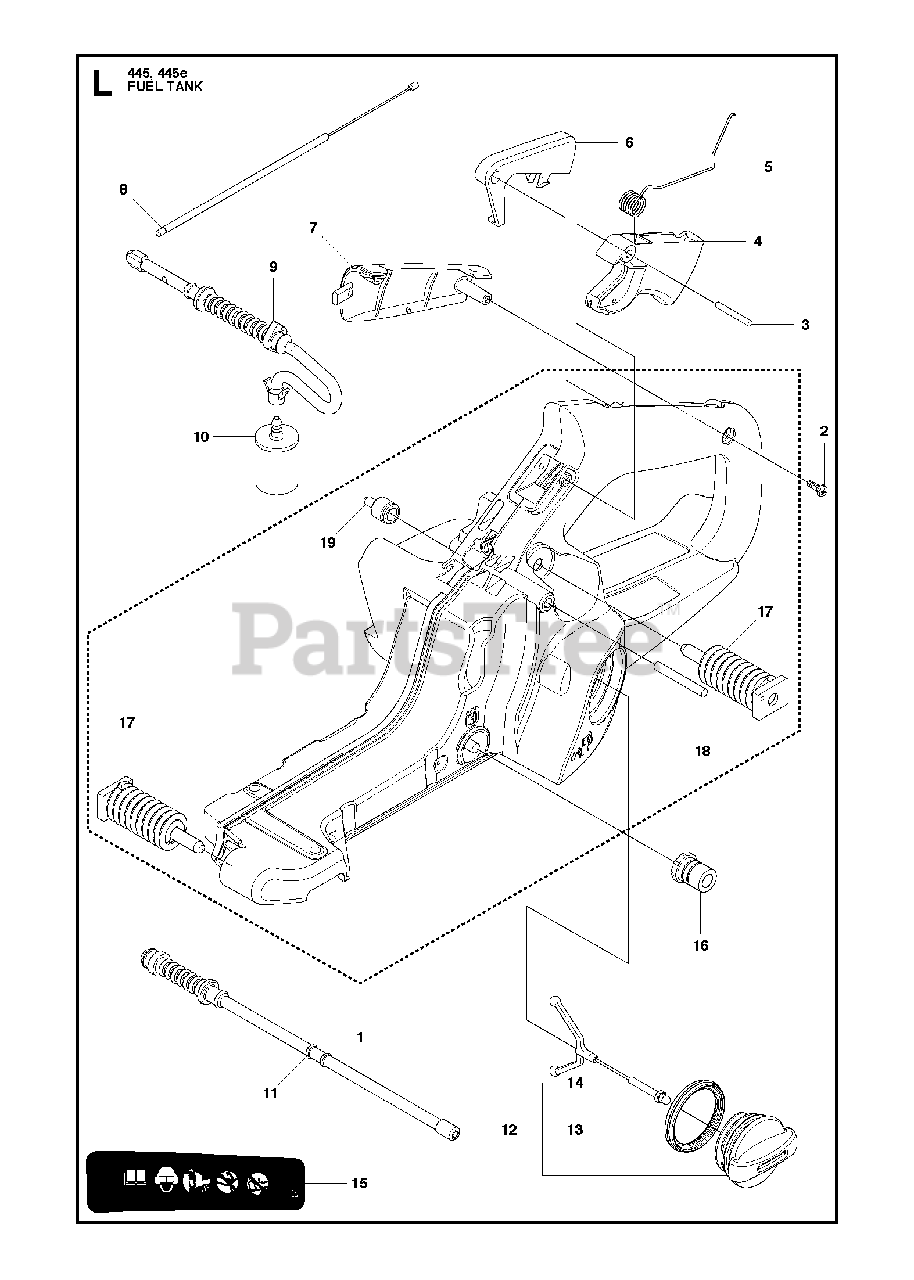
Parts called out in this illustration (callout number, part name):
1	ASSY FUEL TANK
4	THROTTLE TRIGGER
6	THROTTLE LOCKOUT
7	HANDLE INSERT
8	THROTTLE CABLE ASSY
10	FUEL FILTER
11	RP RETURN HOSE
12	TANK CAP ASSY
13	SEALING
14	TANK LOCK
16	LATERAL SUPPORT
17	ANTI VIBRATIONS ELEMENT
18	GROOVED PIN
19	FUEL TANK VENT
